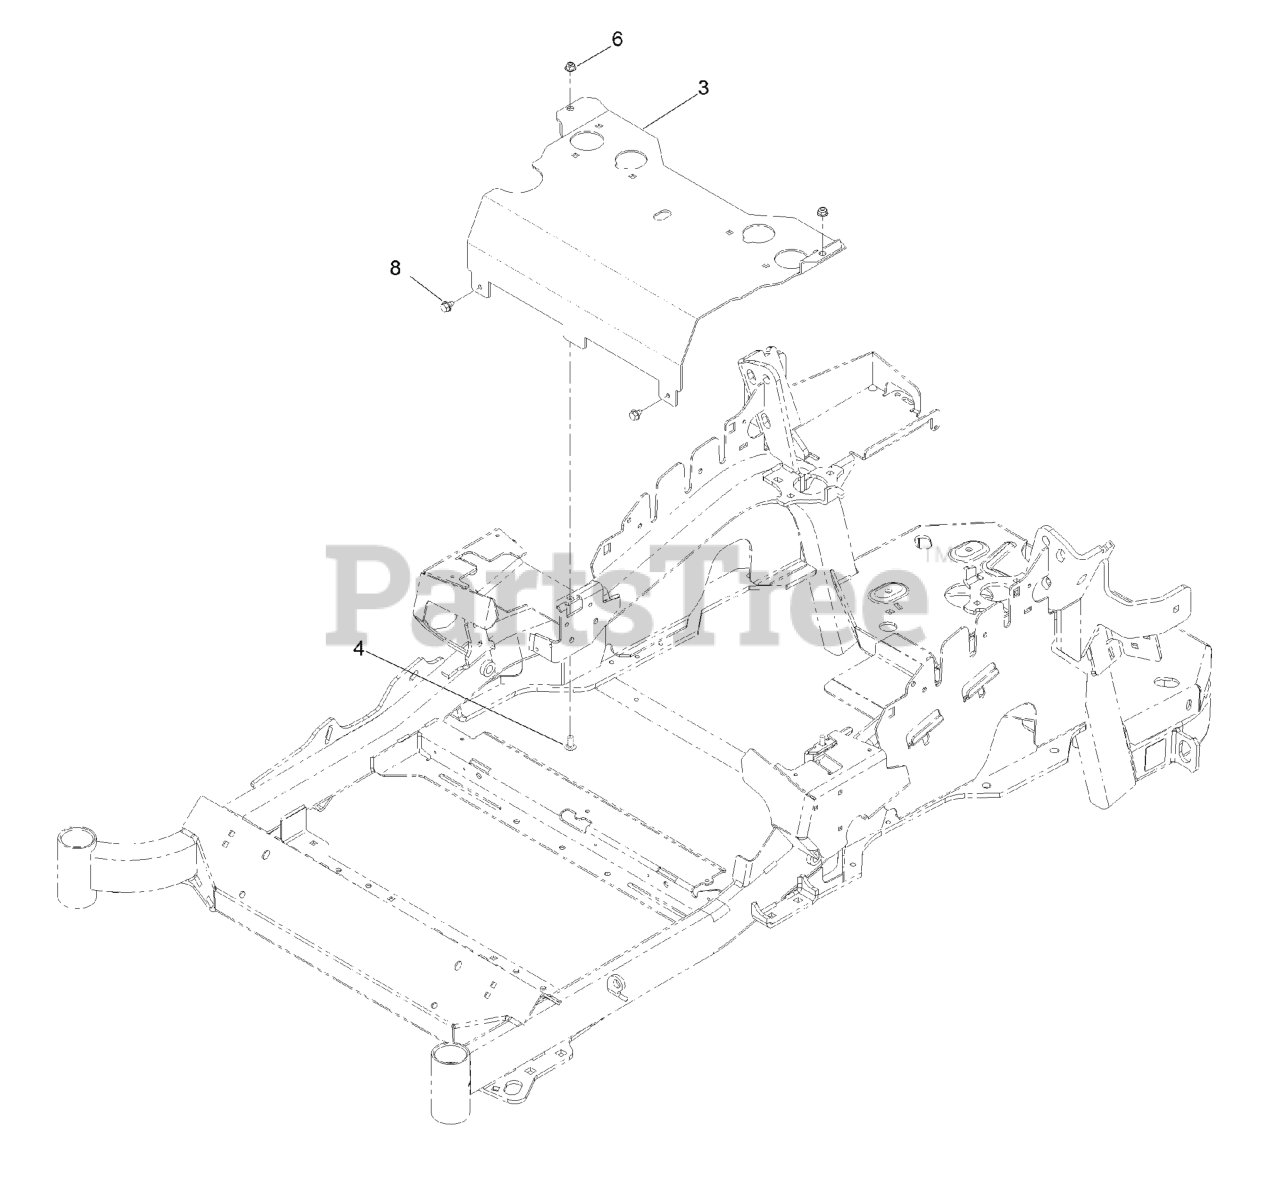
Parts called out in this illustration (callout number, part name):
3	Panel-Front, Seat Mount
4	SCREW-CARR
6	NUT-HF, NI
